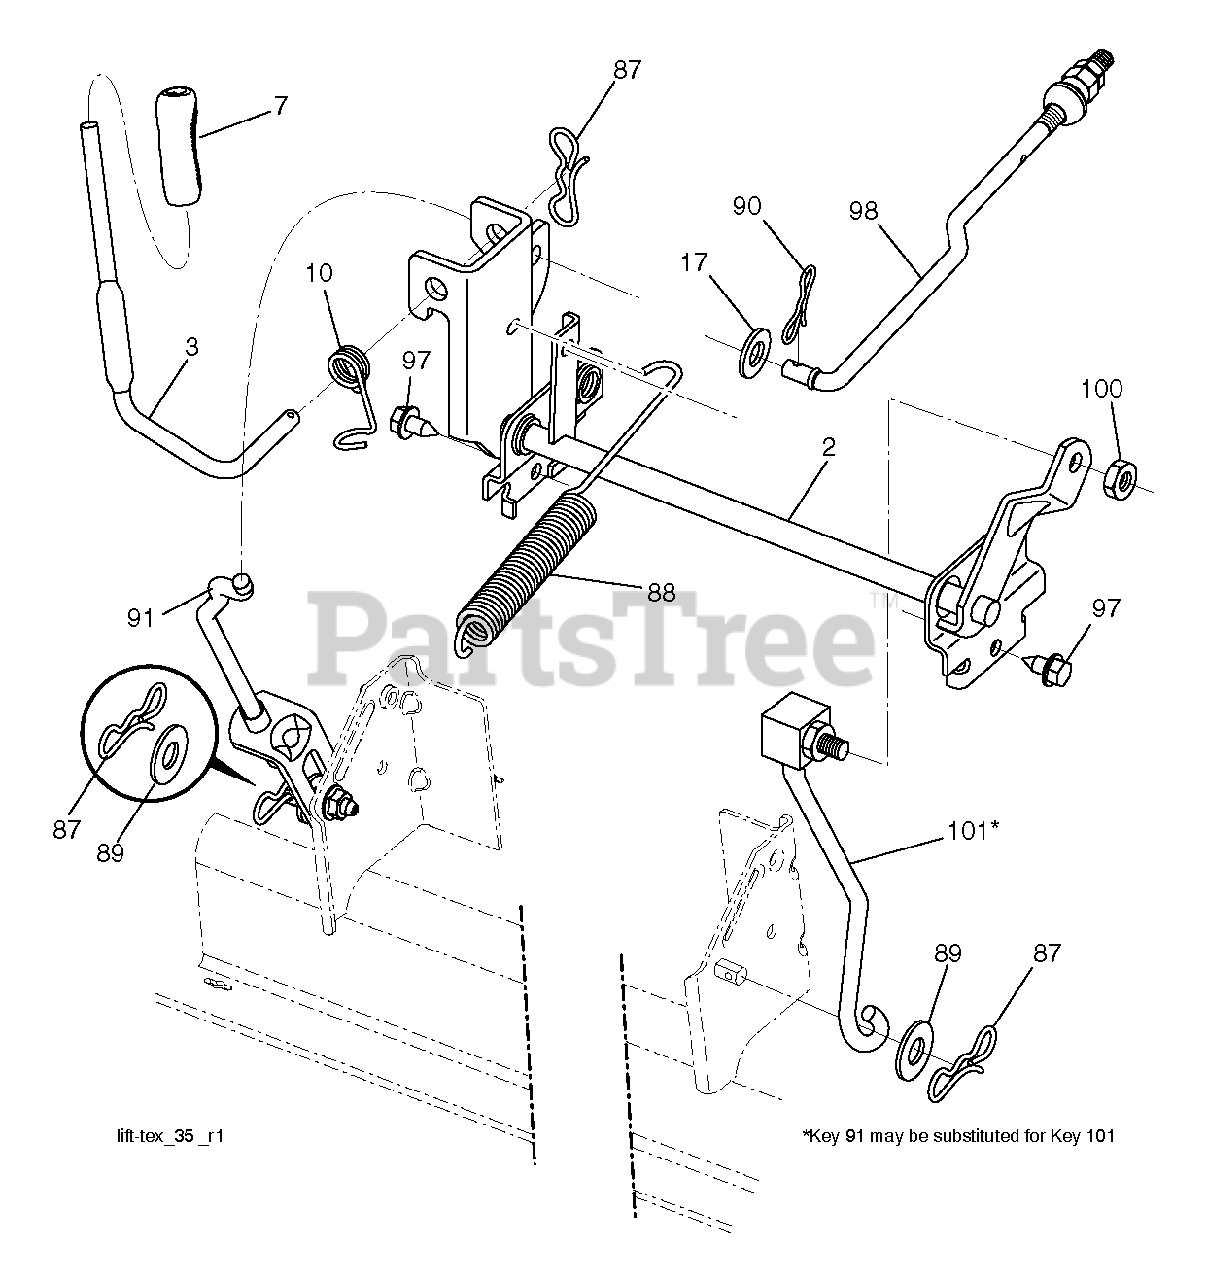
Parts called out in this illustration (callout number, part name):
2	SHAFT.ASM.CROSS.LIFT
3	LEVER.LIFT.HANDLE.LT
10	SPRING.TORSION.LIFT.HANDLE
17	WASHER
87	PIN.COTTER.7/16.BOW TI
88	SPRING.LIFT.ASSIST
89	WASHER.CLEAR.ZINC
90	PIN.COTTER.5/16.BOW TI
91	LINK.ASM.LIFT.REAR
97	SCREW, 3/8-16X3/4
98	LINK.ASM.SUSP.FRONT.MWR.10.5
100	LOCKNUT
101	LINK.ASM.LIFT.FIXE.38/42/46"
